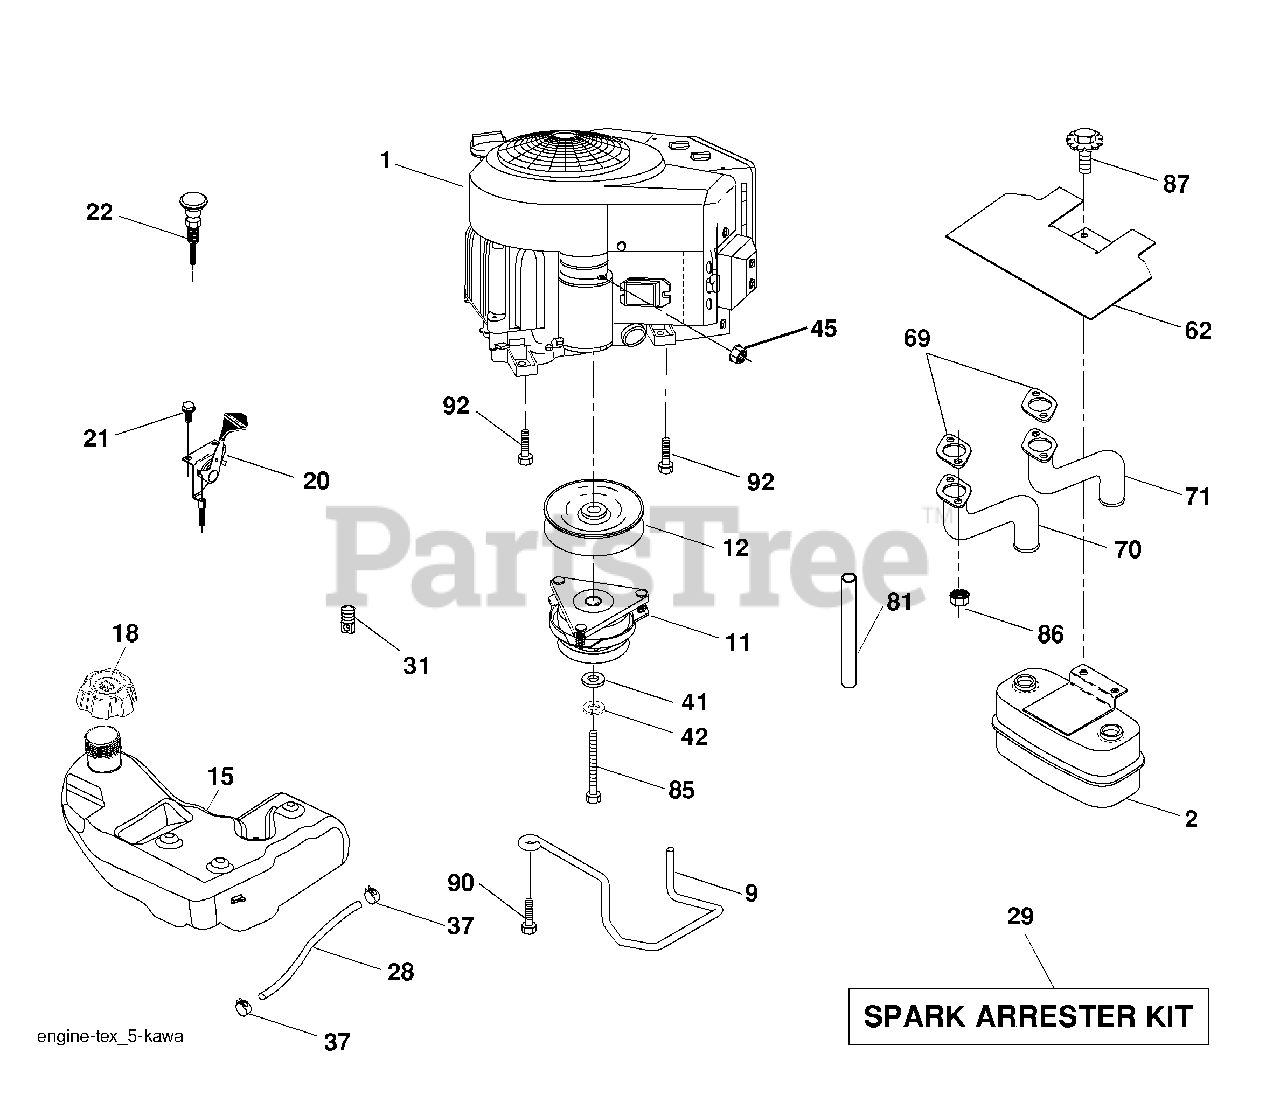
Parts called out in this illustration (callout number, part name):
9	Keeper Belt Engine
11	Clutch Electric
12	Pulley Engine
15	Tank Fuel 4.0
18	Cap Asm
20	Control Throttle
21	Screw #10 x 0.750
22	Control Choke
28	Fuel Line
29	Spark Arrester Kit
31	Clip Push In
37	Clamp Hose
41	Washer 1-1/2 OD x 15/32 ID x .250
42	Washer Lock 7/16
45	Nut Keps Hex 1/4-20unc
62	Shield Heat Muffler
69	Gasket
70	Tube Exhaust LH
71	Tube Exhaust RH
81	Tube Drain Oil Easy
85	Bolt Hex 7/16-20x4 x Gr. 5-1.5
86	Nut Hex Flange Toplock M8-1.2
87	Bolt 5/16-18 unc x 1 w/Sems
90	Screw 3/8-16x1
92	Screw 3/8-16x1
